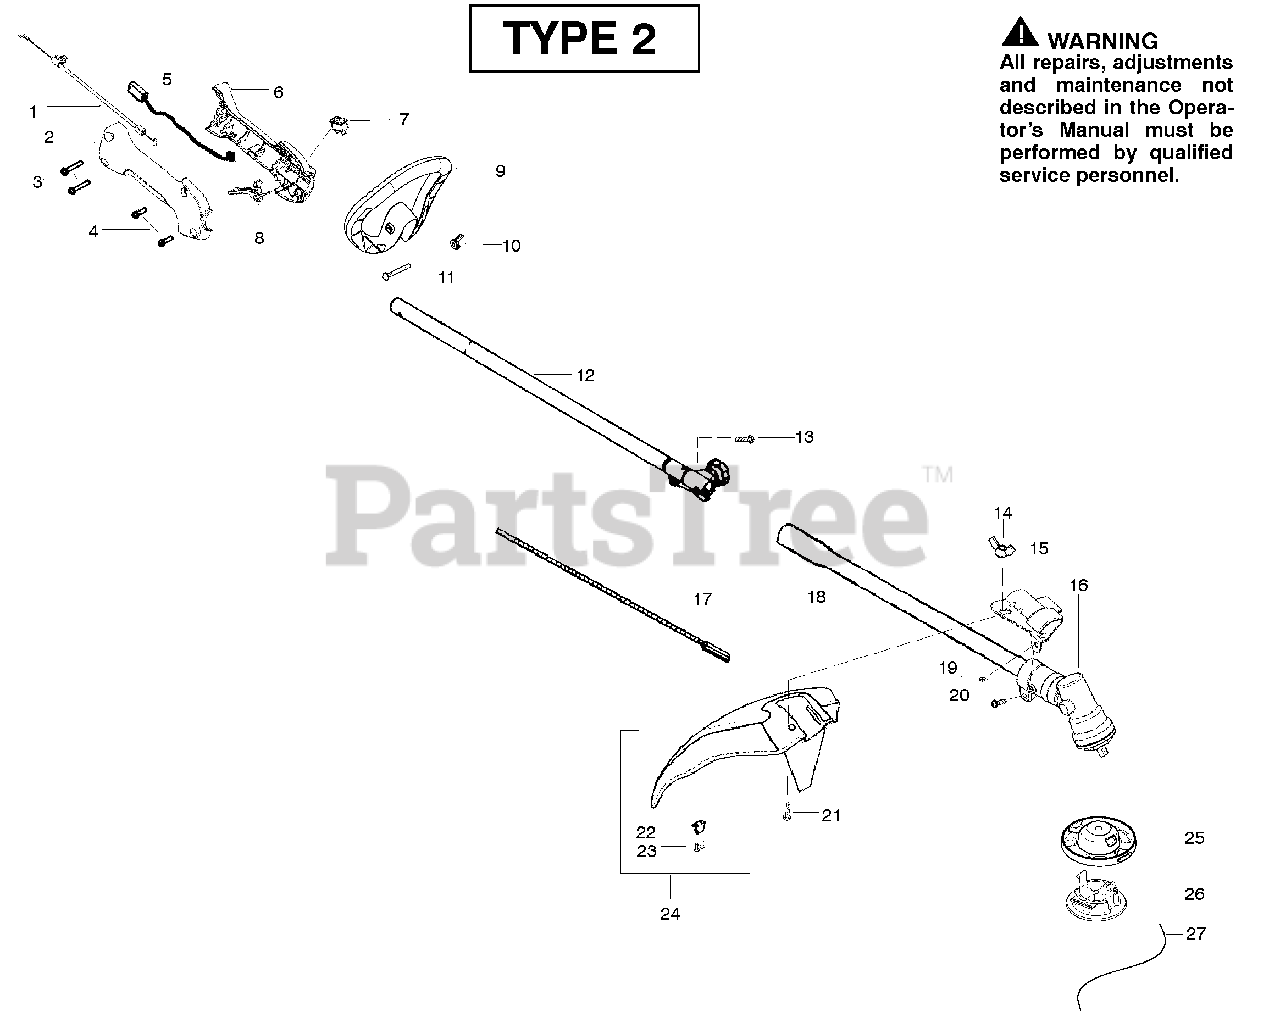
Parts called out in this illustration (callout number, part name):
2	Assy-Throttle Cable
2	Hsg.-Throttle (RH)
5	Assy.-Wire
6	Hsg. Throttle (LH)
7	Kit-Switch
8	Trigger-Throttle
9	Assy.-Handle
10	Wingnut
12	Kit-Upper Shaft
14	Wingnut
15	Bracket-Shield
17	Flexshaft-lower
18	Kit-Lower Shaft
22	Limiter-Line
24	Kit-Shield Assy.
25	Head - Fixed Line
26	Cap - Fixed Line
27	Accy - Line (12 pcs)
